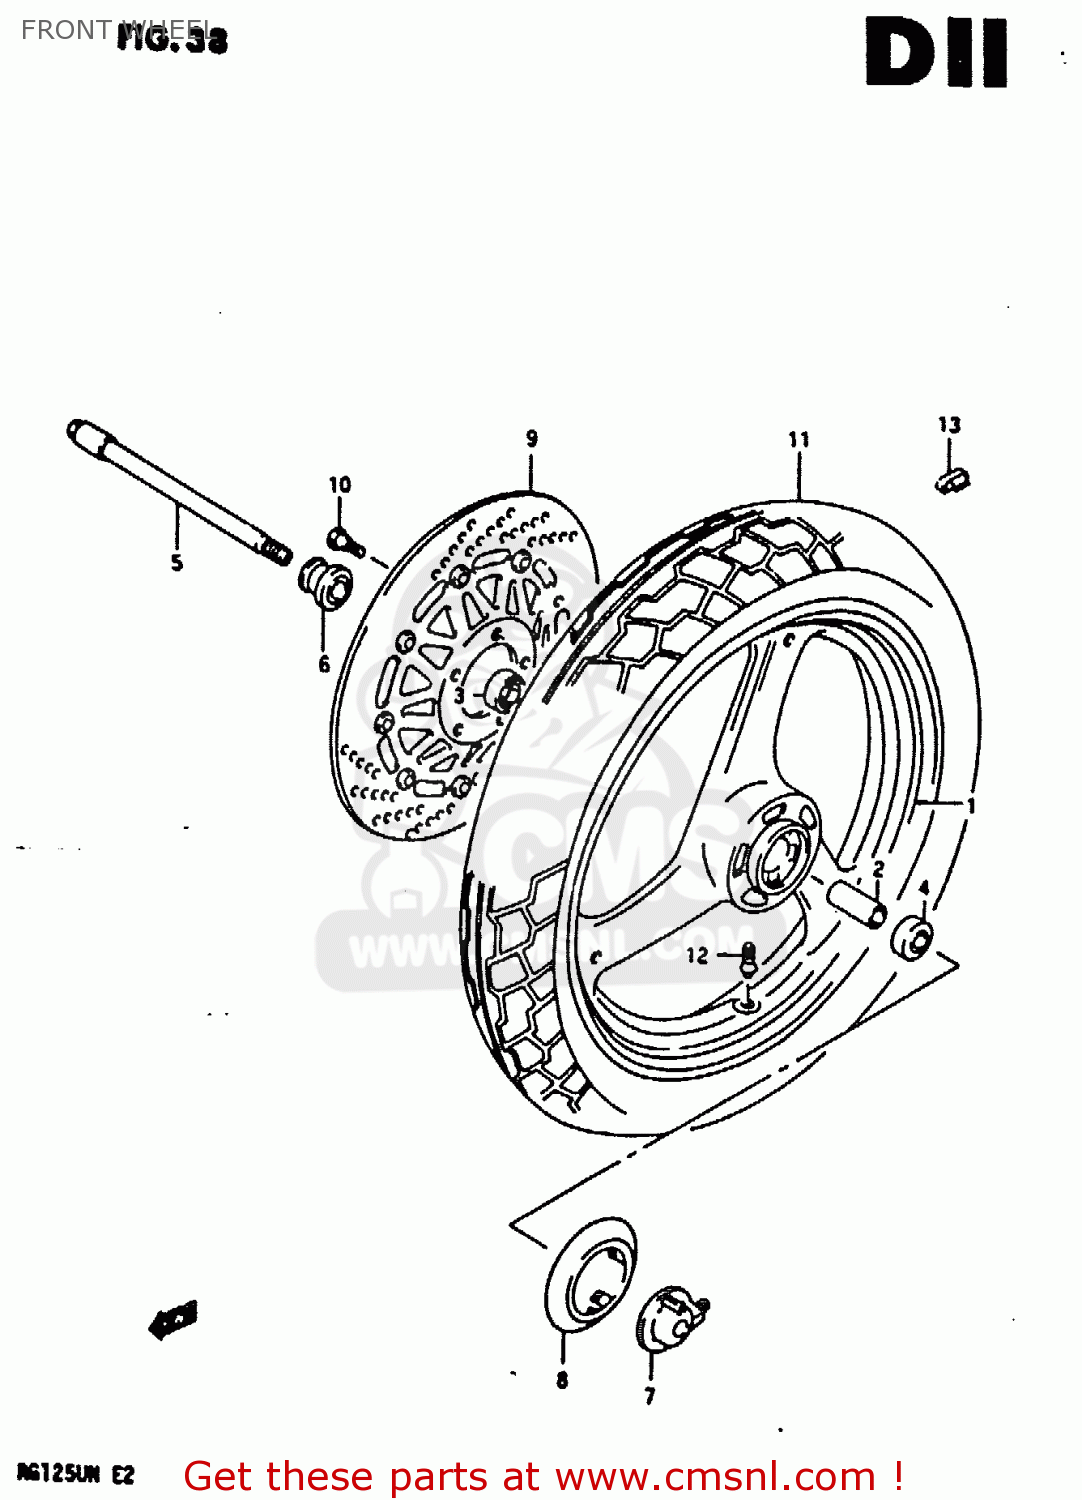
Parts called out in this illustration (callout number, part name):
1	WHEEL, FRONT (17*MT2.50) (RED)
2	SPACER (15.3*21.7*72)
3	BEARING
4	BEARING
5	AXLE,FR
6	SPACER,FRONT AXLE,LEFT
7	BOX ASSY,SPEEDOMETER GEAR
8	COVER,FR HUB,R
9	DISC,FR BRAKE,R
10	BOLT 8X33
11	TIRE, FRONT (100/80-17 525) (DUNLOP)
12	VALVE ASSY,WHEEL RIM(TR412)
13	BALANCER,WHEEL
